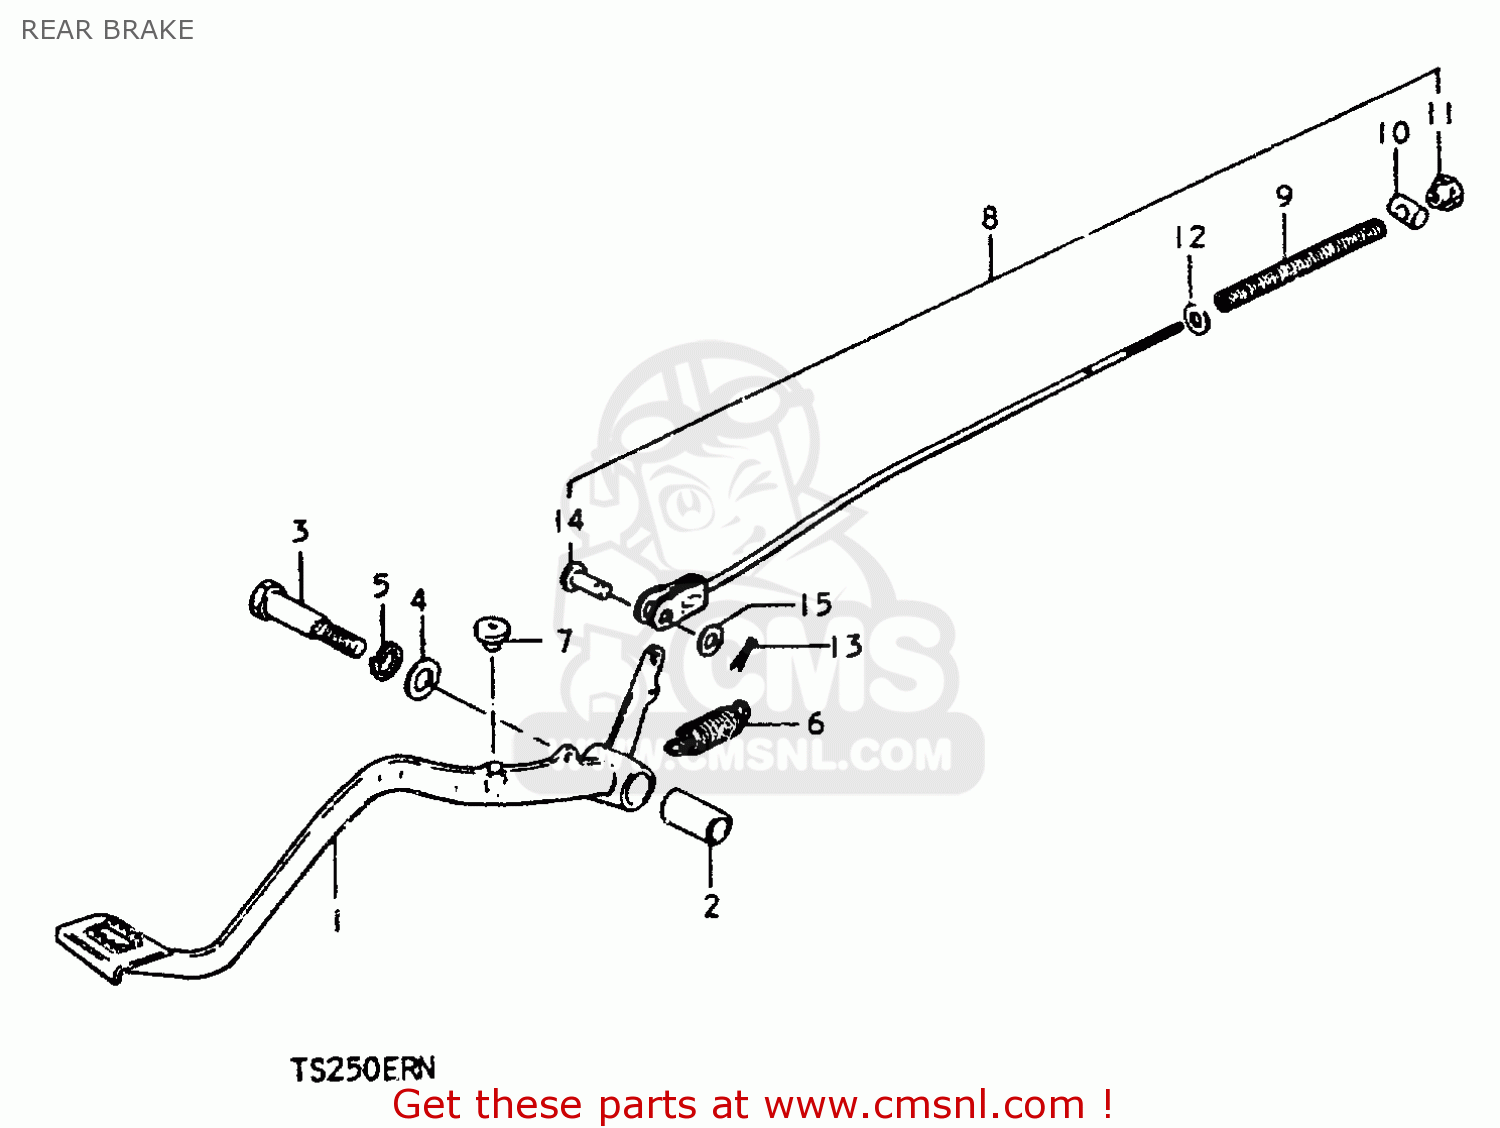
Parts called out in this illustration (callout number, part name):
1	PEDAL,BRAKE
2	SPACER(10.5X16X30)
3	BOLT
4	WASHER
5	LOCK WASHER
6	SPRING
7	STOPPER,BRAKE PEDAL
8	ROD ASSEMBLY,REAR BRAKE
9	SPRING
10	PIN
11	NUT
12	WASHER
13	PIN 20X20
14	PIN(L:13.5)
15	WASHER
